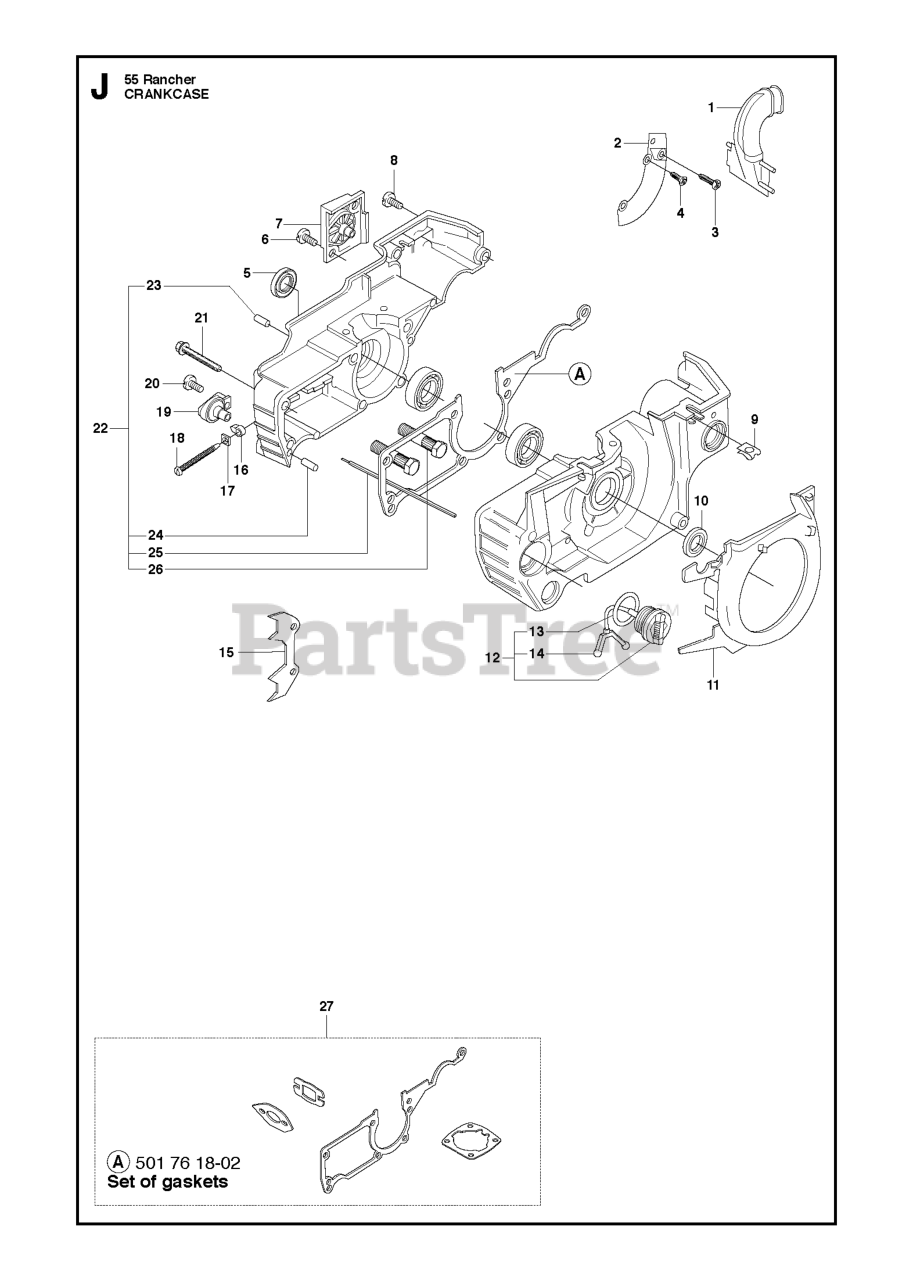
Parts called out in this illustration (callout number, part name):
1	AIR NOZZLE
2	AIR BAFFLE
11	AIR CONDUCTOR
15	FELLING DOG
19	CHAIN CATCHER
21	RP SCREW
23	GROOVED PIN 3X20
24	PIN 5X14
25	OIL TANK VENT
27	GASKET SET
